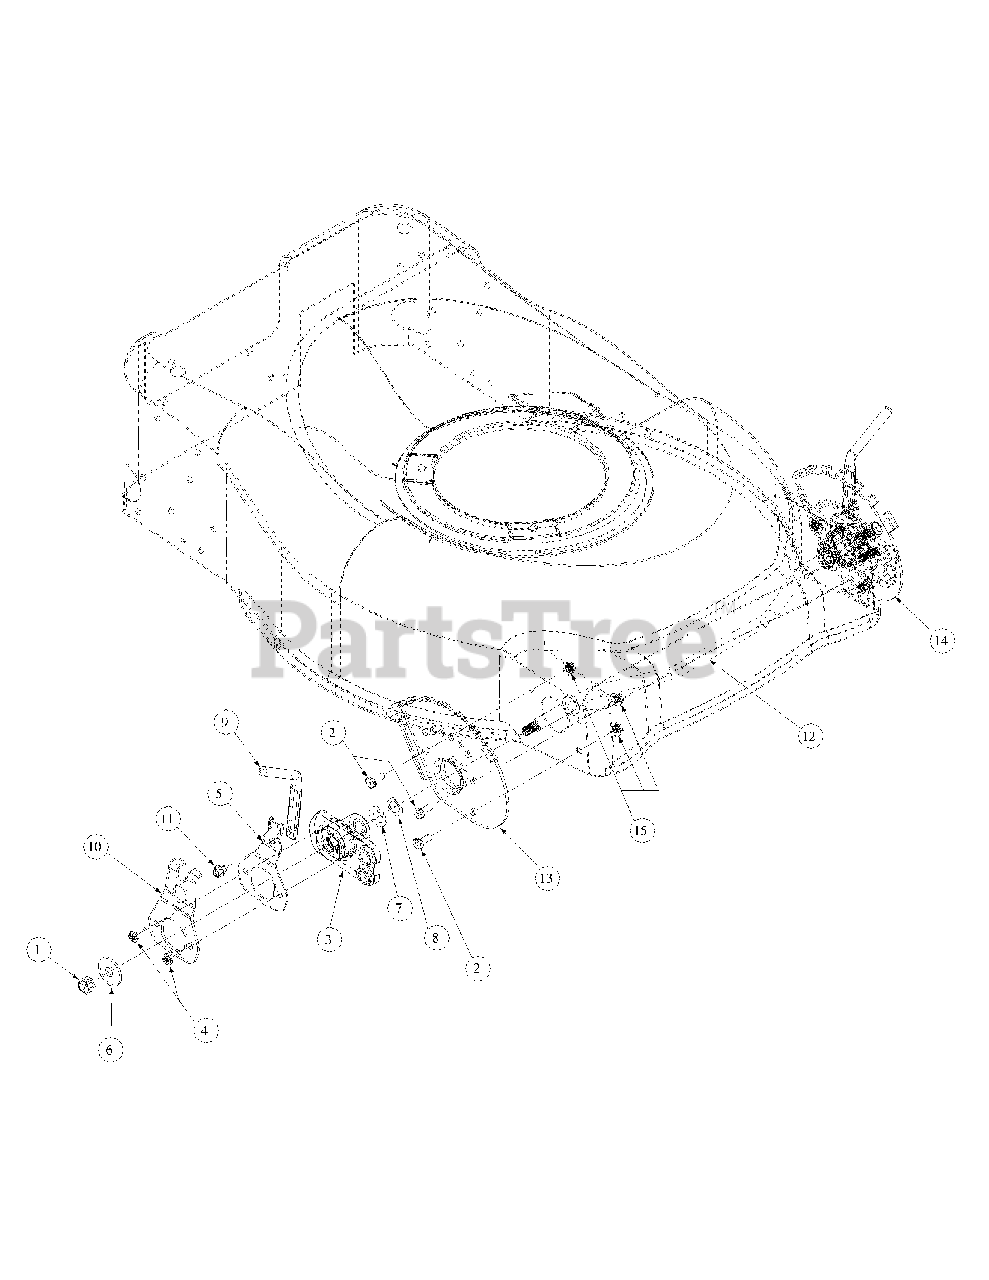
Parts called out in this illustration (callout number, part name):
1	L-Nut,3/8-16, NYL INS. GR A. Z
2	HHCS,1/4-20, .620, GR5, Standard
3	Pivot Wheel Bracket Assembly, 2 POS
4	Screw,TT, 1/4-20, 0.625, PANTRXI
5	Plate, Spring Height Adjuster
6	Flat Washer, .411 x 1 .25 x .100
7	Flat Washer, .536 ID x .930 OD x .05
8	Wave Washer, .531 IDX .781 ODX .01
9	Height Adjustment Handle
10	Spring Lever Support Bracket
11	Screw, TT, 1/4-20, 0.375, Hex Indicator Washer
12	Front Axle, .500 OD
13	Height Adjustment Bracket, Right Front
14	Height Adjustment Bracket, Left Front
15	Nut,1/4-20, Hex Flange, Lock, Group F
